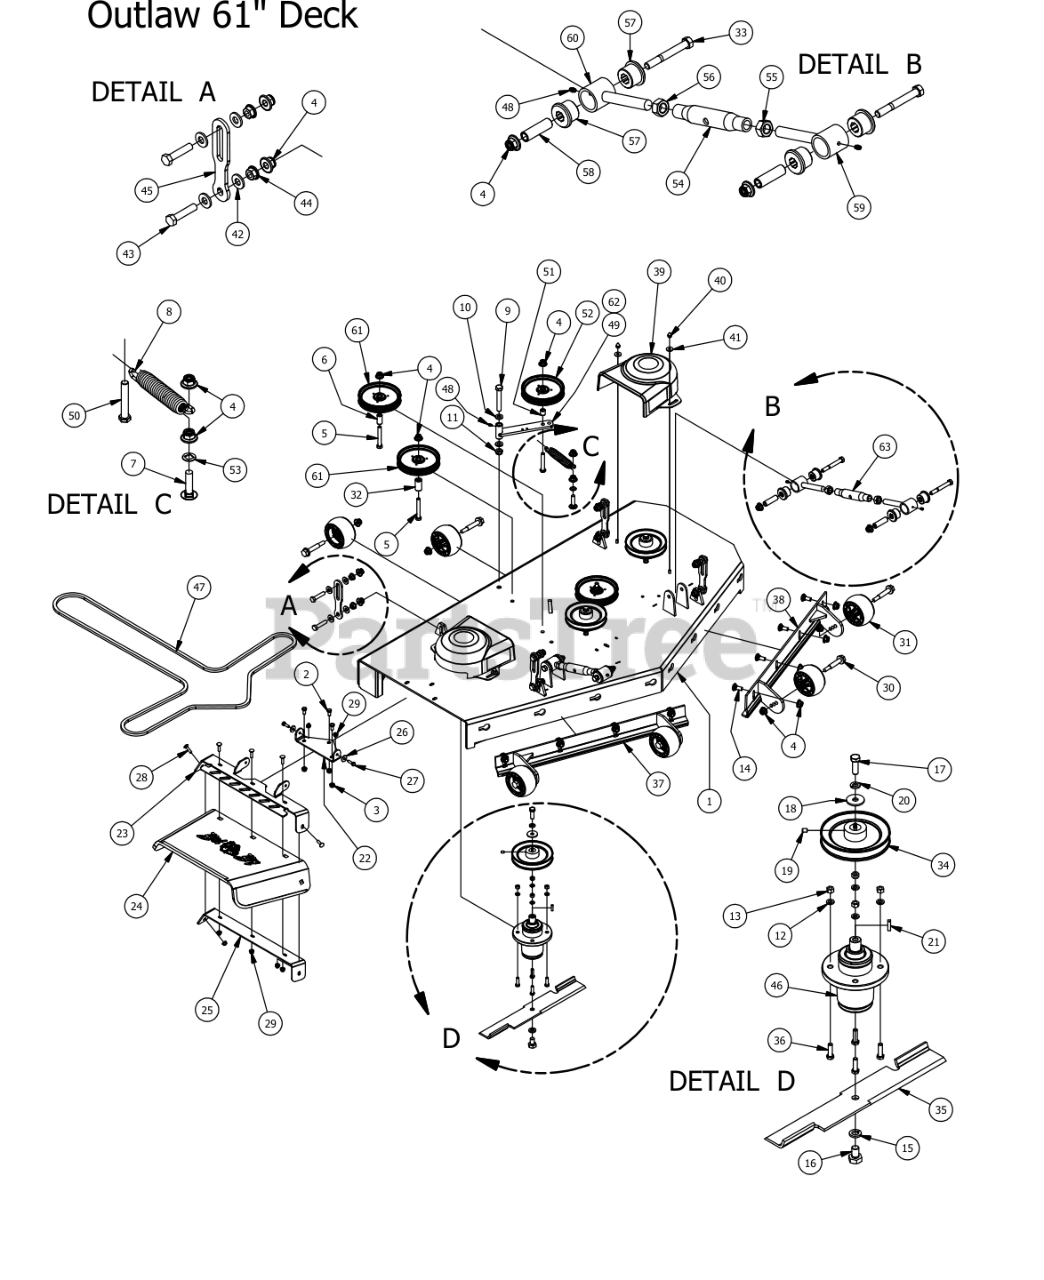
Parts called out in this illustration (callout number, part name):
1	2015 61" Deck
2	3/8" x 3/4" Hex Bolt
3	3/8" Flange Nut
4	1/2-13 Nylon Flange Nut
5	1/2 x 3 1/2 Flange Bolt Grade 8
6	.502 ID X.750 OD X 1.500 Long Spacer
7	1/2 x 2" Carriage Bolt
8	2015 Deck Idler Spring Outlaws
9	5/8" x 4" Hex Bolt
10	.630 ID Plastic Washer
11	5/8-11 Nylon Insert Jam Half Nut
12	3/8 Lockwasher Zinc
13	3/8-16 Hex Nuts Zinc
14	1/2" x 1 1/4 Carriage Bolt
15	5/8" Lock Washer
16	5/8" x 1 1/2" Grade 8 Hex Bolt (Fine)
17	1/2"-20 x 1 1/2 - Grade 5 Fine Thread Bolt
18	1/2 Belleville Washer
19	5/16 Set Screw
20	1/2" Lock Washer
21	1/4" x 1" Key
22	Discharge Chute Hanger (deck mounted)
23	60" Discharge Chute Upper Hanger
24	Rubber Discharge Chute
25	60" Discharge Lower Bracket
26	.360 ID Plastic Washer
27	5/16" x 1" Bolt
28	5/16" x 1 1/4" Carriage Bolt
29	5/16" Nylock Flange Nut Zinc
30	Deck Wheel Bolt
31	Anti-Scalp Rollers
32	1 3/4" Pulley Spacer
33	1/2" x 4" Bolt (Grade 8)
34	6 1/4" Drive Pulley
35	61 inch Fusion Blade
36	3/8" x 1 1/4" Hex Bolt
37	61 Deck Adustable Front (Right)
38	61 Deck Adustable Front (Left)
39	Pulley Cover
40	Acorn nut-pulley Cover
41	.360 ID Plastic Washer-Black
42	.505 Nylon Spacer
43	1/2-13X 2-1/4 GR Hex Bolts
44	1/2" Flange Nut
45	Deck Hanging Tab
46	OUTLAW SPINDLE ASSEMBLY
47	B178 Belt For 61 Inch Outlaw
48	1/4" Press in Grease Fitting
49	Deck Idler
50	1/2-13 x GR 5 Hex Bolt Zinc
51	Spacer 3/4 OD x 1/2 ID x 3\4 Length
52	5-3/4 Idler Pulley-Don Dye
53	.517 Square Hole Round Washer
54	2015 Outlaw Toplink Body
55	3/4-10 Left-Handed Hex Nuts Zinc
56	3/4-10 Hex Nuts Zinc
59	Turn Left-Handed
60	Right-Handed End
61	5-3/4 Idler Pulley-Capitol Stampings
62	Deck Idler Assembly - Includes parts: 4,48,49,50,51
63	Turnbuckle Assembly
